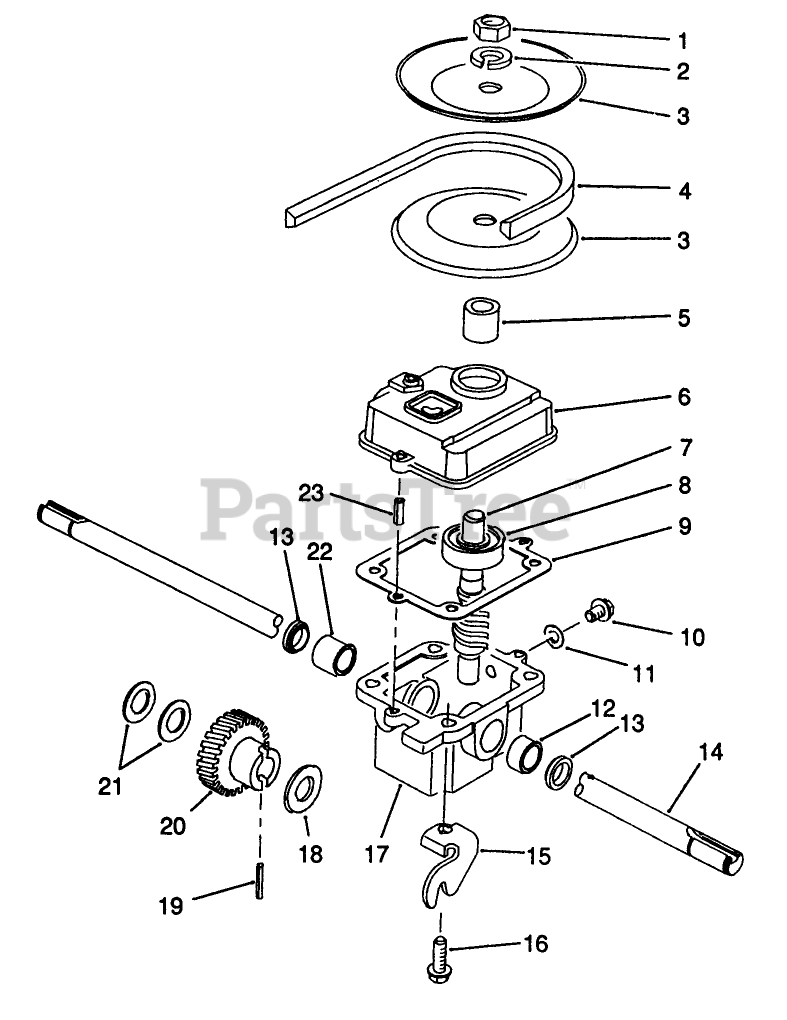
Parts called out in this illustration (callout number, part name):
1	NUT-JAM
2	WASHER-LOCK
3	PULLEY-DRIVEN HALF
8	BEARING - BALL
9	GASKET
10	NYLON SCREW
11	FILL PLUG GASKET
12	BUSHING
13	SEAL-OIL
16	SCREW-HWHTF
18	THRUST WASHER
19	PIN-SPRING
20	GEAR - HELICAL
21	WASHER-PLAIN
22	BUSHING
23	3/16 X 1/2 ROLL PIN
